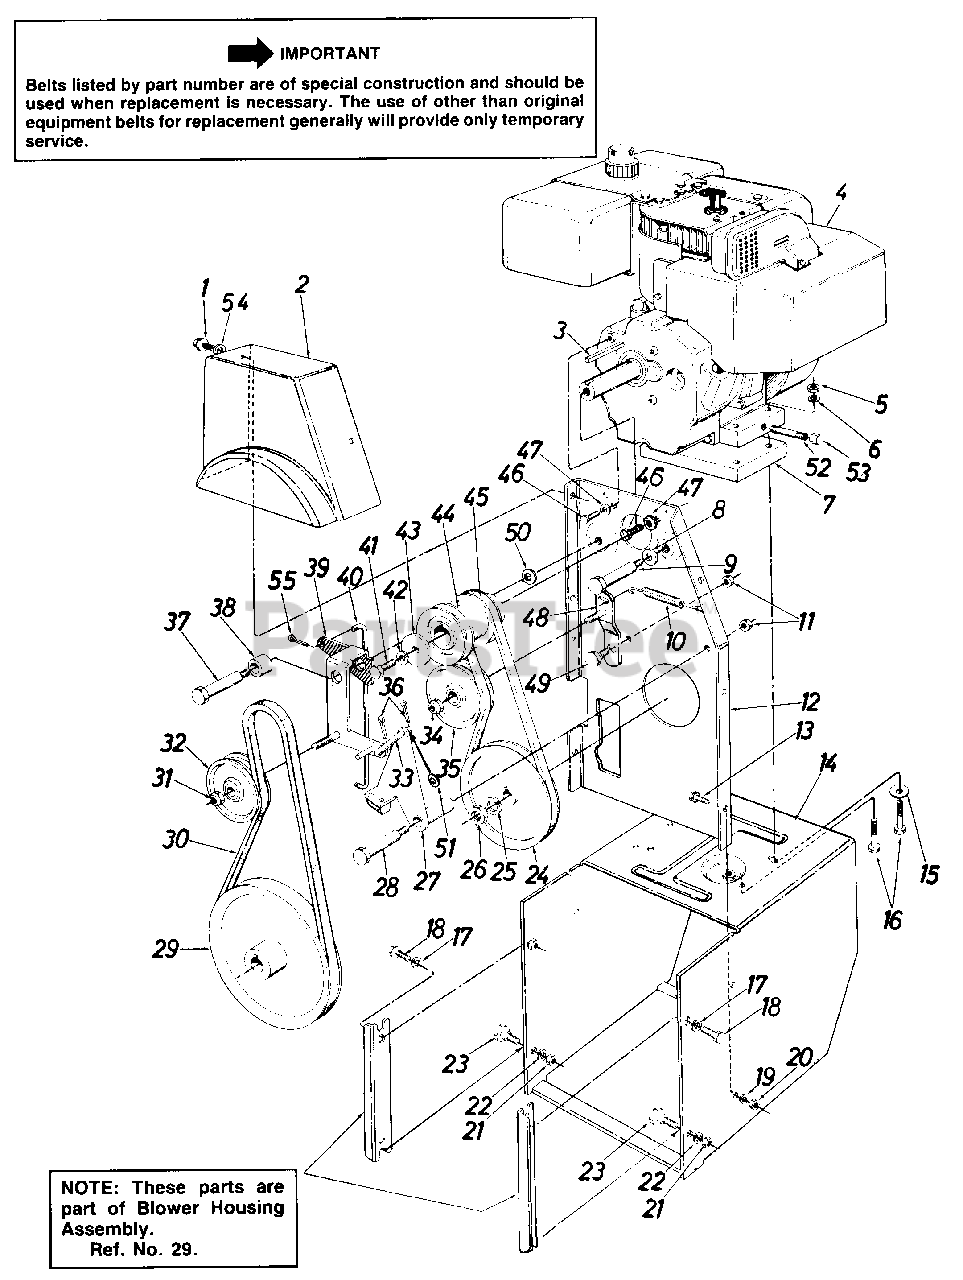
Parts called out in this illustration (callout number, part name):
1	SCREW-HEX HD TAP
2	COVER-BELT
3	KEY-SQ 1/4 x 1.50
5	NUT-HEX 5/16-18
6	WASHER-LOCK-5/16
7	BLOCK-ENGINE SPACER
8	WASHER-BELL .400 ID x .88 x .060
9	SCREW-SHLD .498 DIA x 3.00
10	SPRING-EXTENSION
11	NUT-HEX CENTER L-3/8-16
12	BRACKET ASSY-ENG
13	SCREW-HEX SEMS 5/16-18 x .75
14	FRAME ASSY
15	WASHER-FL-.344 x .62
16	SCREW-HEX
17	WASHER-HDL 3/8
18	SCREW-PILOT 3/8-16 x .88
19	WASHER-LOCK-5/16
20	NUT-HEX 5/16-18
21	NUT-HEX 3/8-16
22	WASHER-HDL 3/8
23	SCREW-SHLD .498 DIA x .340
25	WASHER-LOCK-5/8
26	NUT-HEX INS L-5/8-18
27	BRACKET ASSY-BRAKE
28	SCREW-SHLD .498 DIA x 2.005
29	PULLEY-V-1/2 ID x 10.0 OD
30	BELT-V 1/2 x 45
31	NUT-HEX INS L-3/8-24
32	PULLEY-IDLER-FLAT-3.00
33	LINK ASSY-BRAKE
34	NUT-HEX INS L-3/8-24
35	PULLEY-IDLER-FLAT-3.00
36	PIN-COTTER-3/32 DIA x .75
37	SCREW-SHLD .625 DIA x 2.75
41	SCREW 3/8-24 x 1.25 GR5
42	WASHER-HDL 3/8
43	WASHER-FL
44	PULLEY-ENGINE
45	BELT-3V-35.5
46	SCREW-HEX 5/16-24 x .62
47	WASHER-BELL .337 x .867 x .057
48	BRACKET ASSY-DR IDLER
49	SCREW-SHLD .625 DIA x .163
50	WASHER-BELL .3/8ID x 1.12OD x .030
51	WASHER-FL-.385 ID x .62 OD x .033
52	NIPPLE-PIPE
53	CAP-HEX PIPE THD
54	WASHER-FL-.344 x .62
55	PIN-INTERN COT-5/16 DIA
